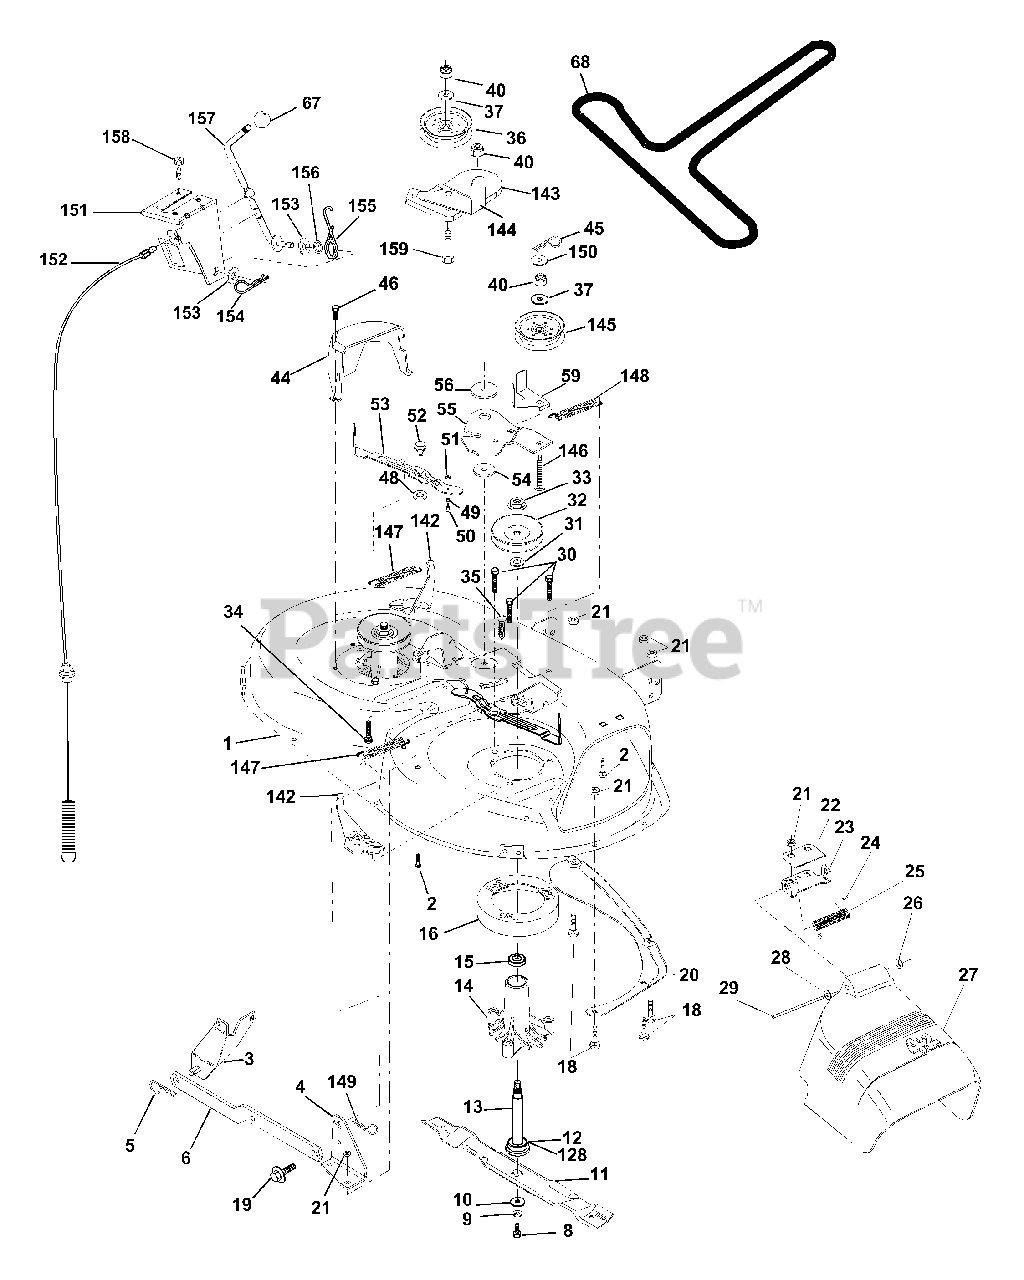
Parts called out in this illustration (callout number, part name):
1	Mower Deck Assembly, 42"
2	Bolt
3	Bracket Asm Fr. Sway Bar 3/42
4	Bracket Asm Deck 42" Sway Bar
5	Retainer Spring
6	Arm, Suspension, Rear
8	Bolt 3/8-24 x 25 Grade 8 patched
9	Washer, Lock
10	Washer,Hardened
11	Blade
12	Bearing, Ball #6204
13	Shaft Assembly, Mandrel, Vented
14	Housing, Mandrel, Vented
15	Bearing, Ball, Mandrel
16	Stripper, Vented Mower Deck
18	Bolt, Carriage 5/16-18 x 5/8
19	Bolt, Shoulder
20	Baffle, Vortex
21	Nut
22	Stiffener Bracket
23	Bracket, Deflector Mower 42"
24	Cap, Sleeve 80 x 112 Blk Mower
25	Spring, Torsion, Deflector 2 52
26	Nut, Push Phos & Oil
27	Shield, Deflector 42" Blk
28	Washer 11/32 x 5/8 x 16 Gauge
29	Rod, Hinge 42" 6 75 W/G
30	Screw Thdrol Washer Head
31	Washer, Spacer Mower Vented
32	Pulley, Mandrel
33	Nut, Toplock 9/16
34	Bolt
35	Fastener, Christmas Tree
36	Pulley, Idler, Flat
37	Washer 13/32 x 13/16 x 16 Gauge
40	Nut
44	Guard, Mandrel, LH
45	Retainer
46	Screw, Thdrol 1/4-20 x 5/8 T
48	Washer,Hardened
49	Roller Assembly, Cam Follower
50	Bolt, Shoulder #10-24 Grade 5
51	Locknut
52	Bolt, Shoulder 5/16-18 UNC
53	Arm Assembly, Pad, Brake
54	Washer,Hardened
55	Arm, Idler
56	Spacer, Retainer
59	Guard TUV Idler
67	Knob
68	V-Belt, 42" Mower
128	Washer, Felt
142	Arm Spring Brake Mower
143	Bracket Arm Idler 42"
144	Keeper Belt 42" Clutch Cable
145	Pulley Idler Flat
146	Bolt Carriage Idler
147	Spring Extension
148	Spring Return Idler
149	Retainer Spring Yellow
150	Washer 9/32 x 3/4 x 16 Ga.
151	Bracket Clutch Cable
152	Clutch Cable 42"
153	Washer Flat 3/8" Type B
154	Spring Retainer
155	Spring Retention LVR CLTCH CAB
156	Spacer Clutch Cable
157	Rod Clutch Cable 3/8"
158	Screw Hex Thd Cut 1/4-20 x 5/8
159	Bolt Rdhd Sqn 3/8-16 UNC x 1-3/4
